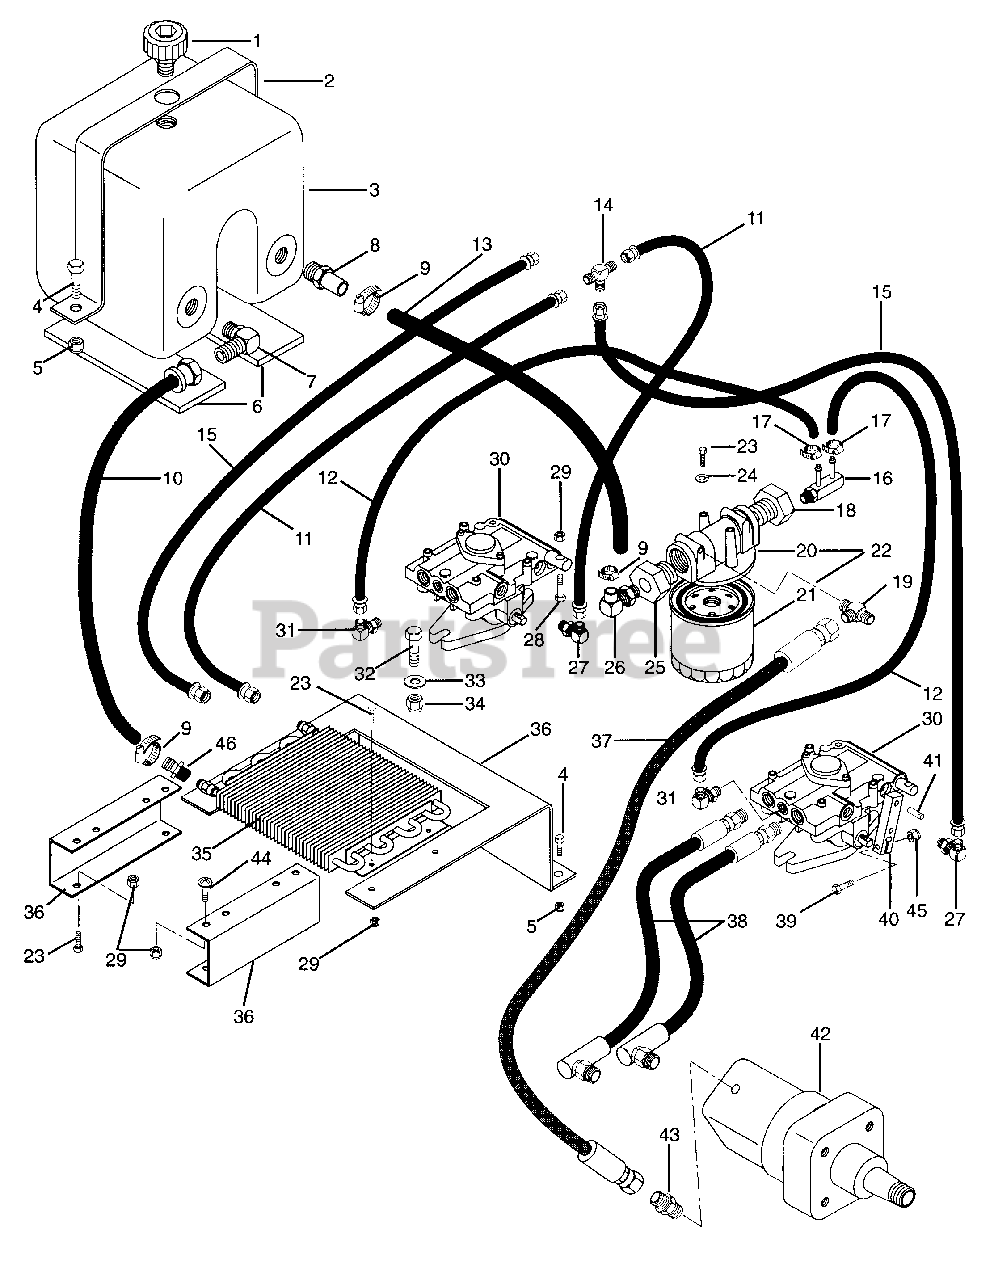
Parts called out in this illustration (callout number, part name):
1	Cap-Filter
2	Strap-Tank
3	Tank-Hydraulic
4	Bolt-Hex .31-18 x .75 Grade 5
5	Nut-Locking-Center .31-18
6	Pad-Gas Tank
7	Adapter .37 x .875
8	Fitting-Adapter 88-14
9	Clamp .88 Diameter Hose
10	Hose-Hydraulic Cooler to Tank
10	Hose-Hydraulic (Oil Cooler to Tank)
11	Hose-Hydraulic Valve to Tank
12	Hose-Oil Filter to Pump
13	Hose .50 Inside Diameter x .75 OD
14	Adapter-Tee .56-18
15	Hose-Pump to Tee
16	Fitting-Pipe .563-18
17	Clamp-Hose 1.50 x .81 x 1.42
18	Adapter-Hydraulic 6410-12-06
19	Adapter-Hydraulic 2601-04-04-04 1
20	Head-Oil Filter
21	Replacement Element 921999
22	Assembly-Filter
23	Bolt-Hex .25-20 x .50 Grade 5
24	Washer-Locking .25 x .062
25	Adapter-Hydraulic .88-14
26	Fitting
27	Adapter 2503-6-6
28	Bolt-Hex .25-20 x 2.00 Grade 5
29	Nut-Locking-Center .25-20
30	Variable Displace Pump 2
31	Adapter 2503-6-4
32	Bolt-Hex .38-16 x 1.25 Grade 5
33	Washer-Flat-Steel .406 x .812 x .065
34	Nut-Locking-Center .38-16
35	Cooler-Oil
36	Bracket-Oil Cooler
37	Hose Assembly-Motor to Oil Filter
38	Assembly-Hose Wheel Motor to Pump
39	Bolt-Hex .25-20 x 1.25 Grade 5
40	Arm-Pump Actuating
41	Pin-Dowel .312 x 1.25
42	Motor-Wheel
43	Adapter 0503-4-4
44	Screw-Machine-Hex-Washer-Head .25-20 x .75
45	Nut-Locking-Center .25-20
46	Adapter-Male .38 x .50
